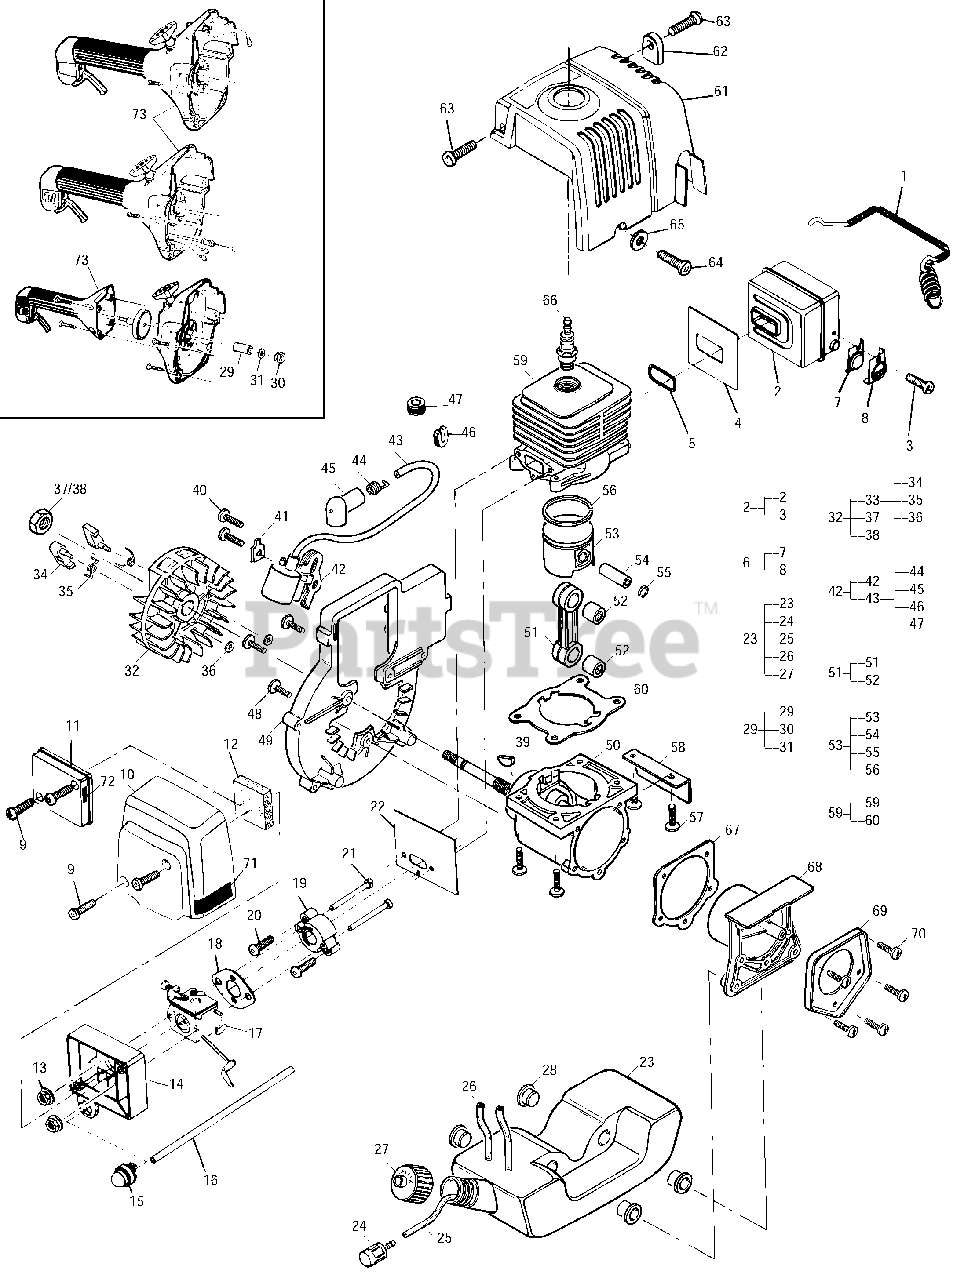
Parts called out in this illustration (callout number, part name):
1	Spring, Muffler
2	Kit, Muffler
3	Screw, 8-18 x .31 Pn Dh Sl Torx
4	Gasket, Muffler
5	Gasket, Exhaust Port
6	Kit, Spark Arrester
7	Screen, Spark Arrester
8	Cover, Spark Arrester
9	Screw, 10-24 x .625, Plast
10	Cover, Air Cleaner, Large (Black)
11	Cover, Air Cleaner, Small (Black)
12	Filter, Air
13	Nut, 10-24 Hex, Flange
14	Box, Air (Blk)
15	Primer, Remote
16	Hose, Fuel Return
17	Carburetor w/Choke
18	Gasket, Carburetor
19	Insulator, Carburetor
20	Screw, 10-24 x .88 Thd Form
21	Screw, 10-24 Spl
22	Gasket, Manifold
23	Tank, Fuel (Natural)
24	Filter, Fuel
25	Hose, Fuel
26	Hose, Fuel Return
27	Cap, Fuel, w/Retainer
28	Isolator, Fuel Tank
29	Kit, Spacer, Clutch
30	Nut, Hex, 7/16-20
31	Washer, Shaft
32	Kit, Flywheel, 28/32
33	Kit, Pawls/Flywheel
34	Pawl, Starter
35	Spring, Starter Pawl
36	Ring, Retainer
37	Nut, Direct Drive
38	Nut, 7/16-20, Clutch Drive
39	Key, Flywheel
40	Screw, 10-24 x .88 Thd Form
41	Terminal Tab
42	Ignition Asy
43	Kit, Spark Plug Wire
44	Connector, Spark
45	Boot, Spark Plug
46	Grommet, H/T Lead, Split
47	Grommet, S/Plug Wire
48	Screw, 10-24x.63 Sl Tor Tp
49	Shroud, Engine
50	Short Block Asy, Direct Drive
50	Short Block Asy, Clutch Drive
51	Rod, Connecting Asy
53	Piston, 28cc Aluminum
53	Piston, 32cc Aluminum
54	Pin, C'shaft Piston
55	Ring, Retaining
56	Ring, Piston
57	Screw, 10-24 x .688 Tri Rnd
58	Shield Muffler
59	Cylinder/Gasket, 28cc Chrome
59	Cylinder/Gasket, 32cc Chrome
60	Gasket, Cylinder
61	Cover, Cylinder/Muffler (Black)
62	Washer, Plastic
63	Screw, 10-24 x .63 Sl Torx Tp
64	Screw, 10-14 x 1.38 Taptite
65	Washer, .469OD/.222ID
66	Spark Plug, RDJ8J
67	Gasket, C'case
68	Plug, C'case
69	Plate, C'case, Coated Finish
70	Screw, 10-24 x .688 Tri Rnd
71	Label, Choke (Vertical)
72	Label, Staring Inst (Eng)
73	Starter/Clutch Housing Asy
